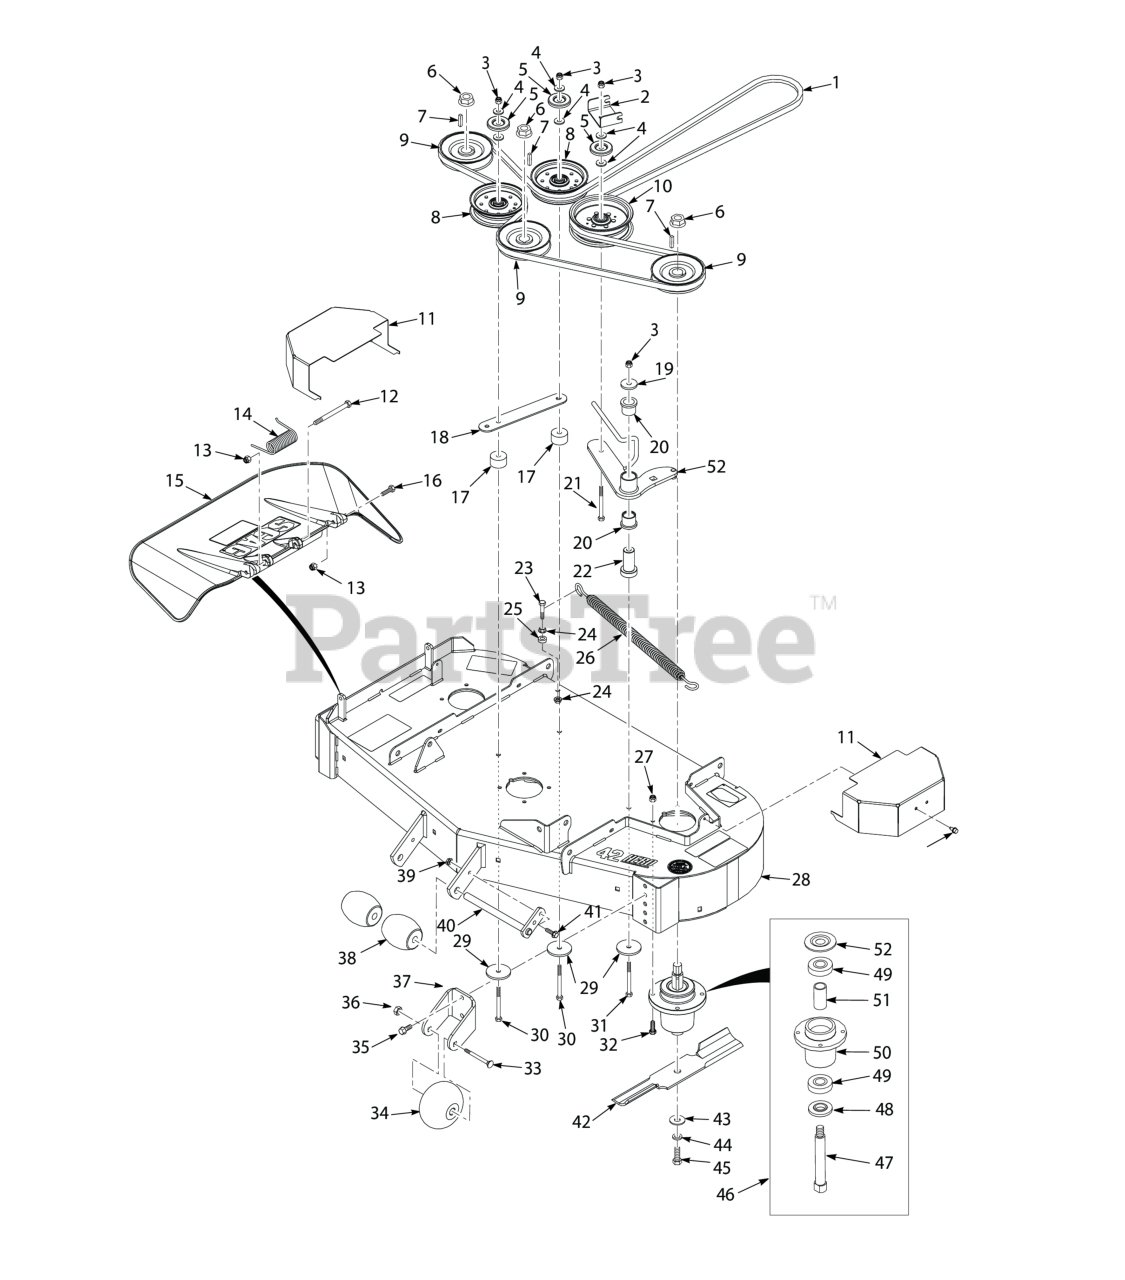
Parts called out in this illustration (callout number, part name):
1	Belt, Cutter Deck
2	Bracket, Belt Guide
3	HEX NUT, ELASTIC STOP LOCK, 3/8-16
4	Flatwasher, 3/8 (.391 x .938 x .105 HD) Grade 8
5	Quick Pin, 5/16" Dia.
6	Nut, 3/4-16 Spriral Lock
7	Key, 1/4 x 1/4 x 1.25" Pulley Mtg.
8	Pulley, Idler 4-1/2"
9	Pulley, 4.62"
10	Pulley, 5" Idler
11	Belt Cover
12	Bolt, 5/16-18 x 4-3/4" Hex Head
13	HEX NUT, ELASTIC STOP LOCK, 5/16-18
14	Spring, Discharge Chute
15	Discharge Chute
16	Bolt, Hex Head 5/16-18 x 1-1/2" - Front
17	Spacer, Idler Pulley
18	Brace, Pulley
19	Flat washer, 1/4-.266 x .875 x .125
20	Bearing, Plastic
21	Capscrew, Hex Head 3/8-16 x 2-1/2"
22	Pivot, Idler
23	Bolt, Hex Head 3/8-16 x 1-3/4" Grade 8 Black
24	NUT, 3/8-16 SERRATED FLANGE HEX HEAD
25	SPACER, IDLER
26	Spring, Cutter Deck Idler
27	Lock Nut, 5/16-18 Elastic Stop Grade 8
28	Cutter Deck w/Decals, SZL-42H
29	Flatwasher, 3/8-.406 x 2.25" x .1875
30	Bolt, Hex Head, 3/8-16 x 3-1/2"
31	Bolt, Hex Head 3/8-16 x 4.00
32	Bolt, Hex Head 5/16-18 x 1-1/2" Grade 8
33	Bolt, Hex Head 3/8-16 x 3-1/2"
34	Bolt, Carriage 3/8-16 x 4"
35	Capscrew, 3/8-16 x 1.0" Serrated Flange Hex Hd
36	Bolt, Hex Head 3/8-16 x 1" Ser. Flg.
37	Bracket, Anti-Scalp, (Black)
38	Wheel, Anti-Scalp
39	Nut, Flange Head Elastic Stop 5/16-18
40	Shaft Weldment, Guide Roller
41	Bolt, Heax Head 5/16-18 x 1" (48V / 52V)
42	Cutter Blade, 14-3/4"
43	Flatwasher, 5/8-.688 x 1-3/4 x .134 HD
44	Lockwasher, 5/8" Spring
45	Bolt, Hex Head 5/8-11 x 1-1/2"
46	Spindle Assembly
47	Shaft, Spindle
48	Protector, Bearing
49	Bearing
50	Spindle Housing
51	Spacer, Bearing
52	Idler Arm Assy. (incl. #20)
